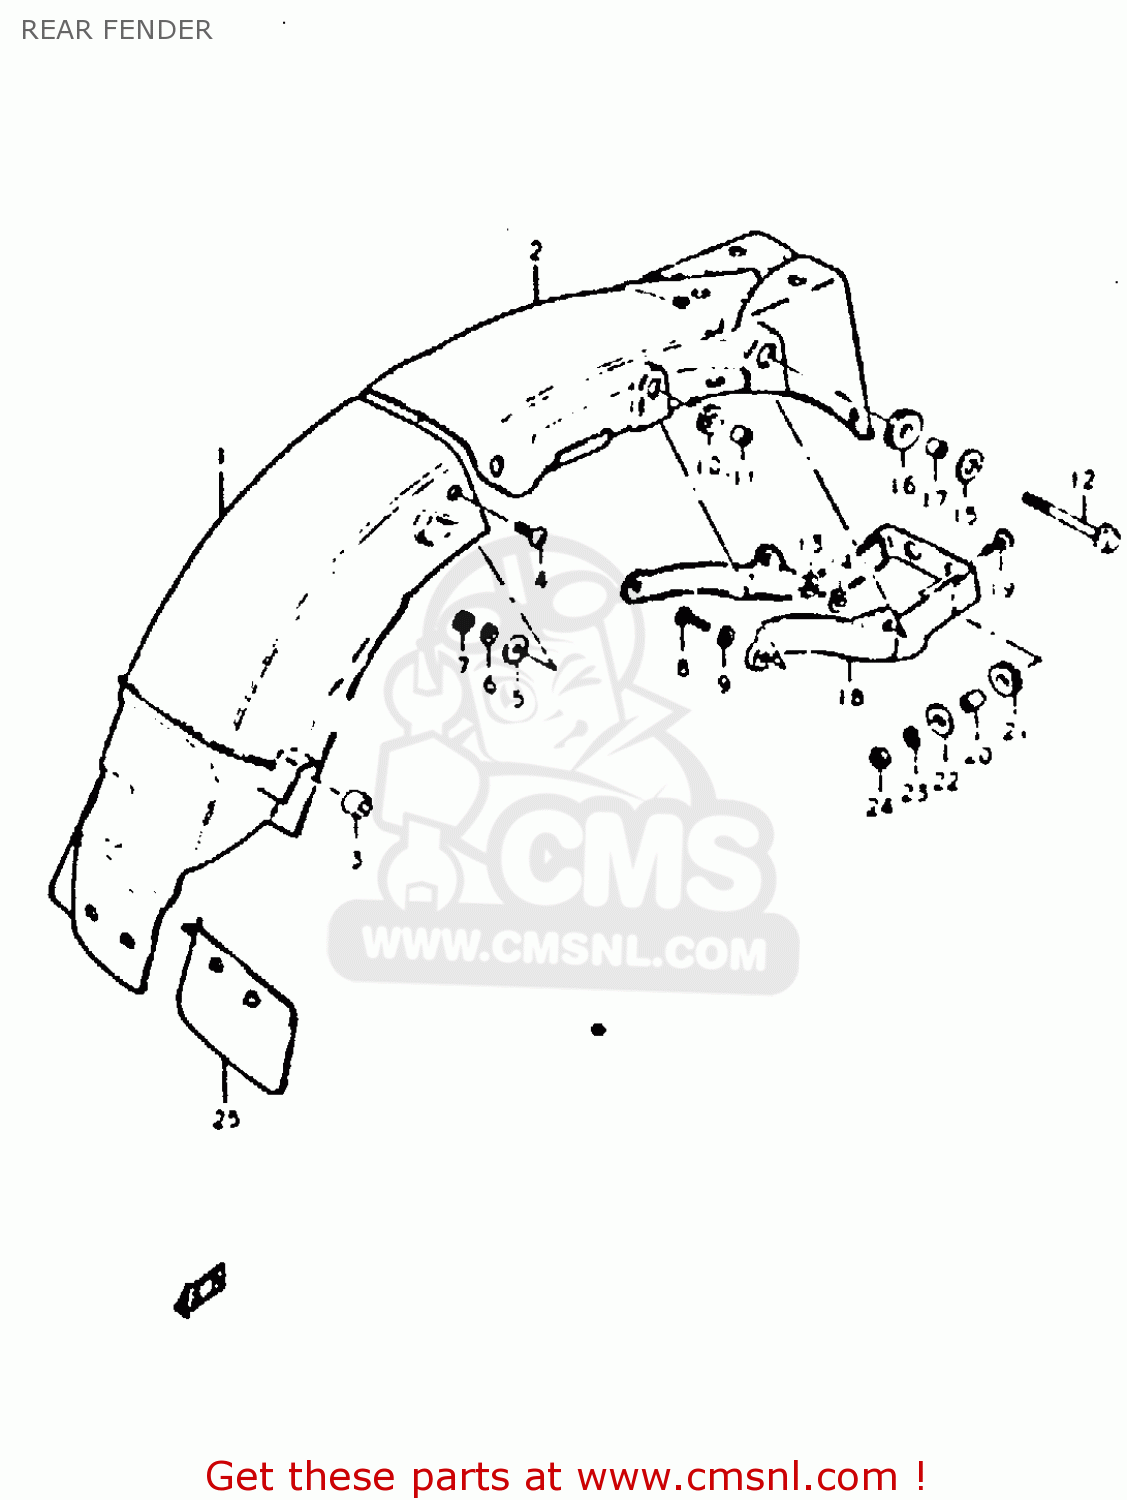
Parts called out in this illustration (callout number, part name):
1	FENDER,REAR
2	BODY,RR FENDER RR
3	CUSHION
4	SCREW
5	WASHER (5.5X16X1.2)
6	LOCK WASHER
7	NUT
8	BOLT
9	LOCK WASHER
10	CUSHION
11	SPACER(6.1X9X7.5)
12	BOLT
13	NUT
14	LOCK WASHER
15	WASHER(8.5X26X1.2)
16	CUSHION
17	SPACER (8.2X12X7.5)
18	REINFORCEMENT,REAR FENDER
19	SCREW
20	SPACER (6.1X9X9)
21	CUSHION
22	WASHER(6,5X22X1.6)
23	LOCK WASHER
24	NUT
25	MUD GUARD,REAR FENDER
